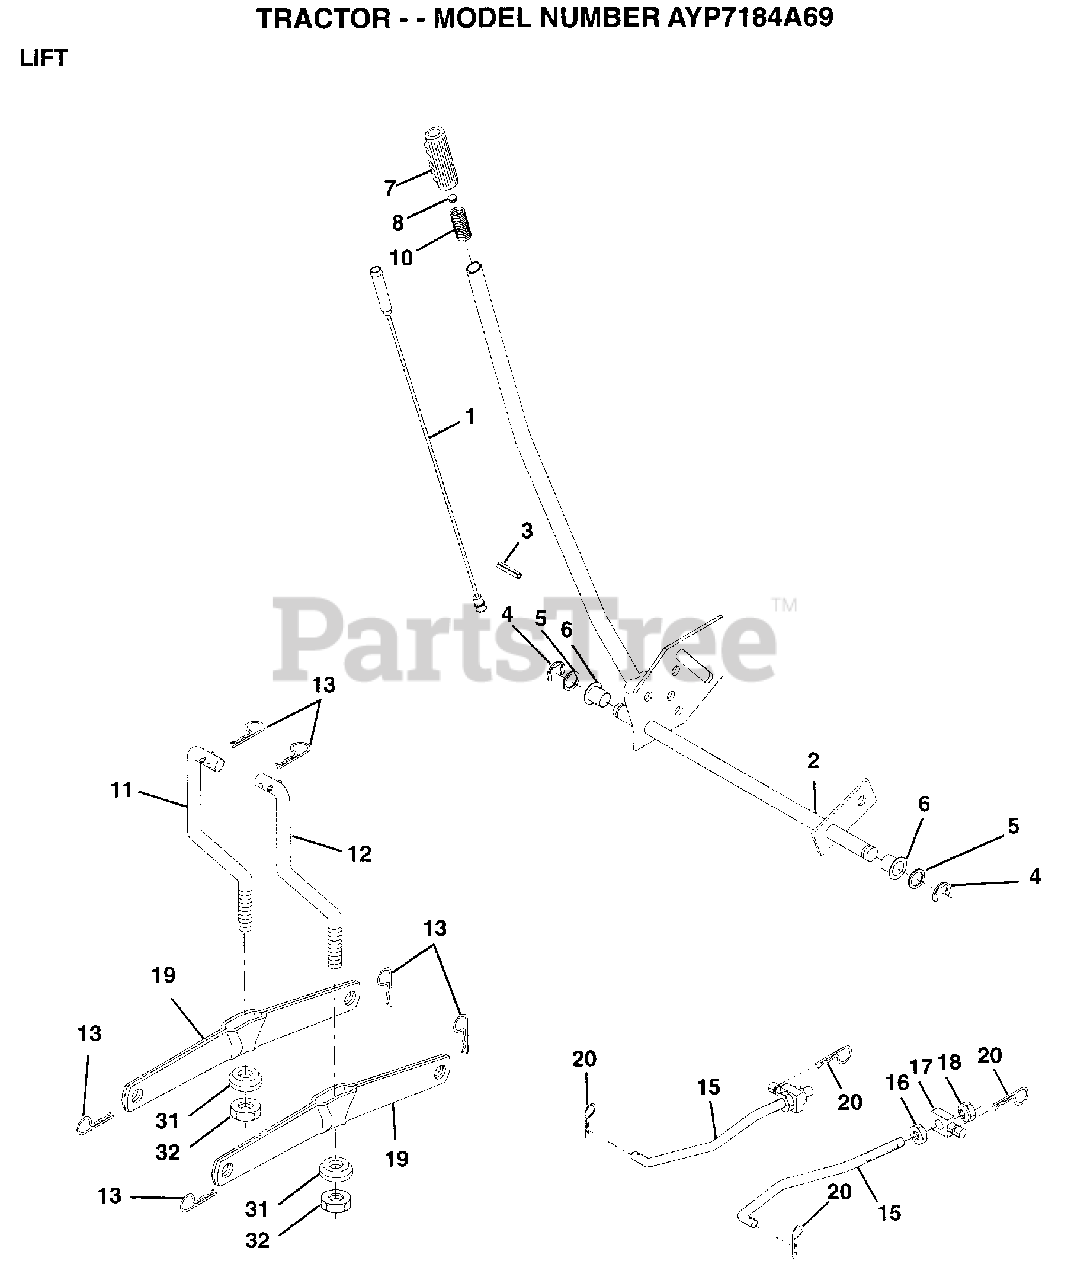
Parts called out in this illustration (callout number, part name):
1	WIRE ASM
2	HANDLE.LIFT.LH.
3	PIN GROOVE
5	WASHER
6	NYLON BEARING
7	GRIP
15	LINK.FRONT
16	NUT
17	TRUNION
18	NUT.LK.W/WSH.1/2.
19	ARM SUSP REAR
20	RETAINER.SPRING
31	BEARING PVT LH
32	NUT.CROWNLOCK.3/8
